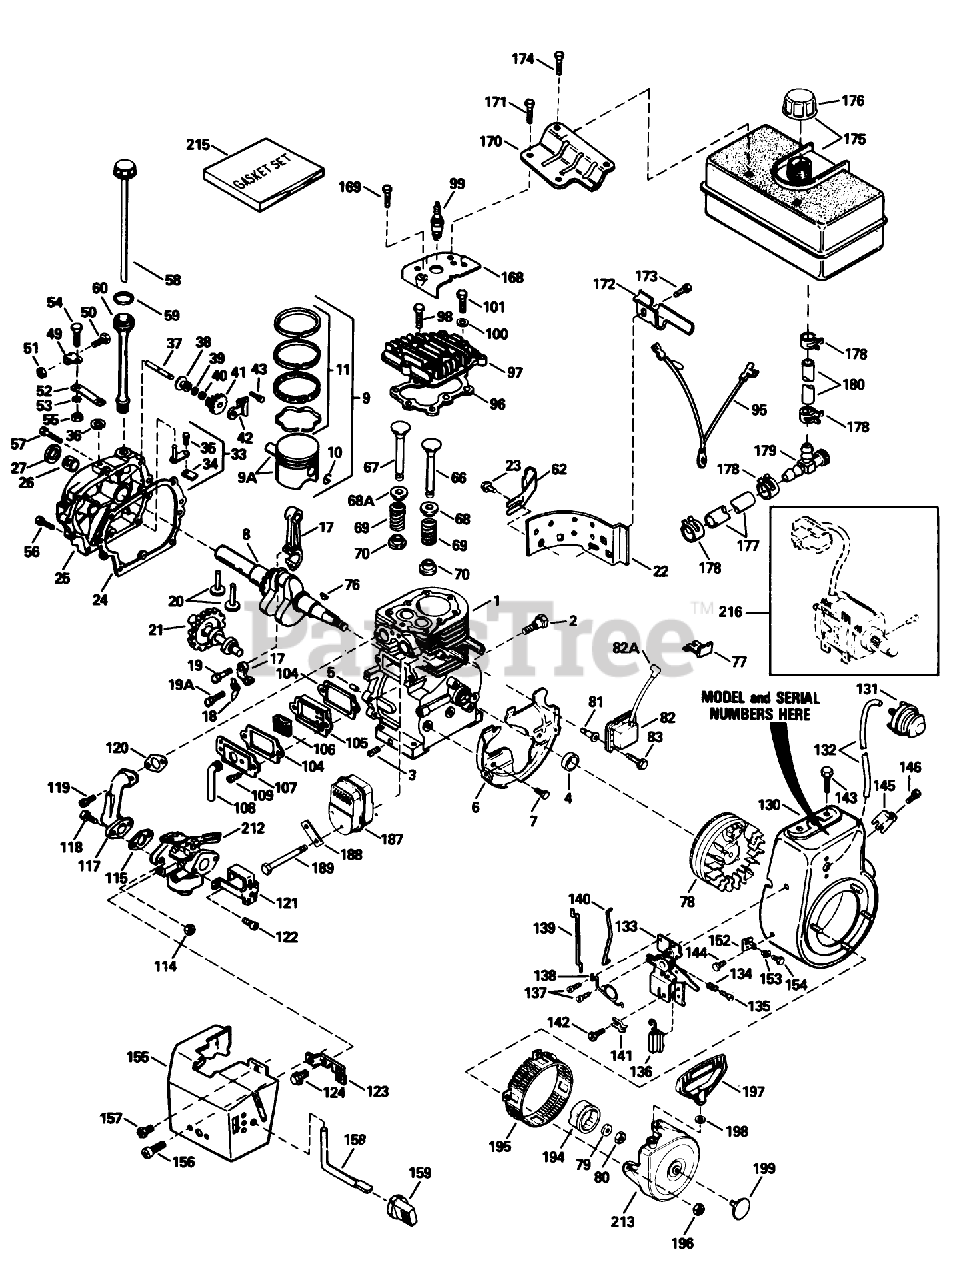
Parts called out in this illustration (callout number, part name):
1	Cylinder Asm (Includes 2, 20, 72)
2	Screw (1/4-20x1/2)
3	Plug-Pipe
4	Seal-Oil
5	Pin-Dowel
6	Baffle-Blower Housing
7	Screw (1/4-20x19/32)
8	Crankshaft
9	Piston, Pin Ring Assy.(Std.) (Incl. Ref. #24A, 25 26)
9	Piston, Pin Ring Assy. (.010 oversize) (Incl. Ref. #24A, 25 26)
9	Piston, Pin Ring Assy. (.020 oversize) (Incl. Ref. #24A, 25 26)
9A	Piston Pin Assy. (Std.) (Incl. Ref. #26)
9A	Piston Pin Assy. (.010 oversize) (Incl. Ref. #26)
9A	Piston Pin Assy. (.020 oversize) (Incl. Ref. #26)
11	Wire Ground
11	Ring Set (.010" OS)
11	Ring Set (.020" OS)
17	Rod Assy., Connecting (Incl. Ref. #28 28A)
18	Dipper-Oil
19	Bolt-Rod
19A	Bolt-Rod
20	Lifter-Valve
21	Camshaft (MCR)
22	Extension-Housing, Blower
23	Screw
24	Cylinder Cover Gasket
25	Cover-Cylinder (Includes 71, 75, 80)
26	2025A77 WIZARD ROTA
27	Seal-Oil
33	Rod, Governor (Incl. Nos.62 63)
34	Yoke-Governor
35	Screw (6-40x5/16)
36	Ring-Retaining
37	Shaft-Governor
38	Spool-Governor
39	Washer
40	Ring-Retaining
41	Gear Assy., Governor (Incl. Ref. #45)
42	Bracket-Gear, Governor
43	Screw (10-24x1/2)
49	Clamp-Lever, Governor
50	Screw
51	Nut-Lock
52	Lever-Governor
53	Washer-Lock
54	Screw
55	Nut-Lock
56	Screw (1/4-20x1-11/16)
57	Screw (1/4-20x1-3/16)
58	Dipstick
59	O-Ring
60	Tube-Fill, Oil
62	Clip-Tube, Fill
66	Valve, Exhaust (Standard)(Incl. No. 9)
66	Valve, Exhaust (1/32" oversize)(Incl. No. 9)
67	Valve, Intake (Std.) (Incl. Ref. #58)
67	Valve, Intake (1/32" oversize) (Incl. Ref. #58)
68	Cap-Spring, Valve
68A	Seal-Intake Valve
69	Spring-Valve
70	Keeper-Spring, Valve
76	Key-Flywheel
77	Clip-Wire
78	Flywheel (W/Ring Gear)
79	Washer-Belleville
80	Nut-Flywheel
82	Solid State ASM
82A	Cover-Spark Plug
83	Screw
95	Ground Wire
96	Gasket-Cylinder Head
97	Head Cylinder
98	Screw (5/16-18x1-1/2)
99	Spark Plug-Resistor (R J19 L M)
100	Washer-Flat
101	Screw (5/16-18x1-25/32)
104	Gasket-Cover, Valve
105	Body-Breather
106	Element-Breather
107	Cover-Valve
108	Tube-Breather
109	Screw
114	Nut and Lock Washer (1/4-28)
115	Gasket-Carburetor To Intake Pipe
117	Pipe-Intake
118	Screw (1/4-28x1)
119	Screw (T-30, 5/16-18x1-3/32)
120	Gasket-Pipe, Intake
121	Bracket-Choke
122	Screw (10-32 x 1/2)
123	Bracket-Carburetor
124	Screw (8-32x27/64)
130	Housing-Blower
131	Primer-Asm
132	Line-Primer
133	Control Assy., Remote Speed (Incl. Ref. #90 thru 93)
134	Spring-Compression
135	Screw
136	Terminal
137	Screw (10-32 x 1/2)
138	Spring-Throttle
139	Link-Governor
140	Link-Throttle
141	Conduit
142	Screw (10-32 x 3/8)
143	Screw (5/16-18x3/4)
144	Screw
145	Screw
146	Screw (8-32 x 3/8)
152	Bracket, Grommet Mounting
153	Grommet
154	Screw (8-32 x 3/8)
155	Cover-Carburetor
156	Screw (10-32 x 3/8)
157	Screw (10-32x1/2)
158	Rod-Choke
159	Knob-Control
168	Cover-Cylinder Head
169	Screw (1/2-20x5/8)
170	Bracket-Tank, Fuel (Black)
171	Screw
172	Bracket-Tank, Fuel
173	Screw (1/4-20x19/32)
174	Screw (1/4-15x7/8)
175	Tank-Fuel (Includes 292, 301)
176	Cap-Fuel
177	Line-Fuel
178	Clamp-Line, Fuel
179	Valve-Shut Off
180	Line-Fuel (8.62)
187	Muffler
188	62513 SNWTHWR W/284
189	Screw
194	Cup-Starter
195	Screen-Starter
196	Nut and Lock Washer (1/4-28)
197	Handle-Starter, Mitten Grip
198	Washer
199	Plug Starter
212	Carburetor (Incl. Ref. #184)
213	Starter-Rewind
215	Gasket Set (Incl. items marked *)
216	Electric Starter Kit. (Optional) Order as an Accessory
